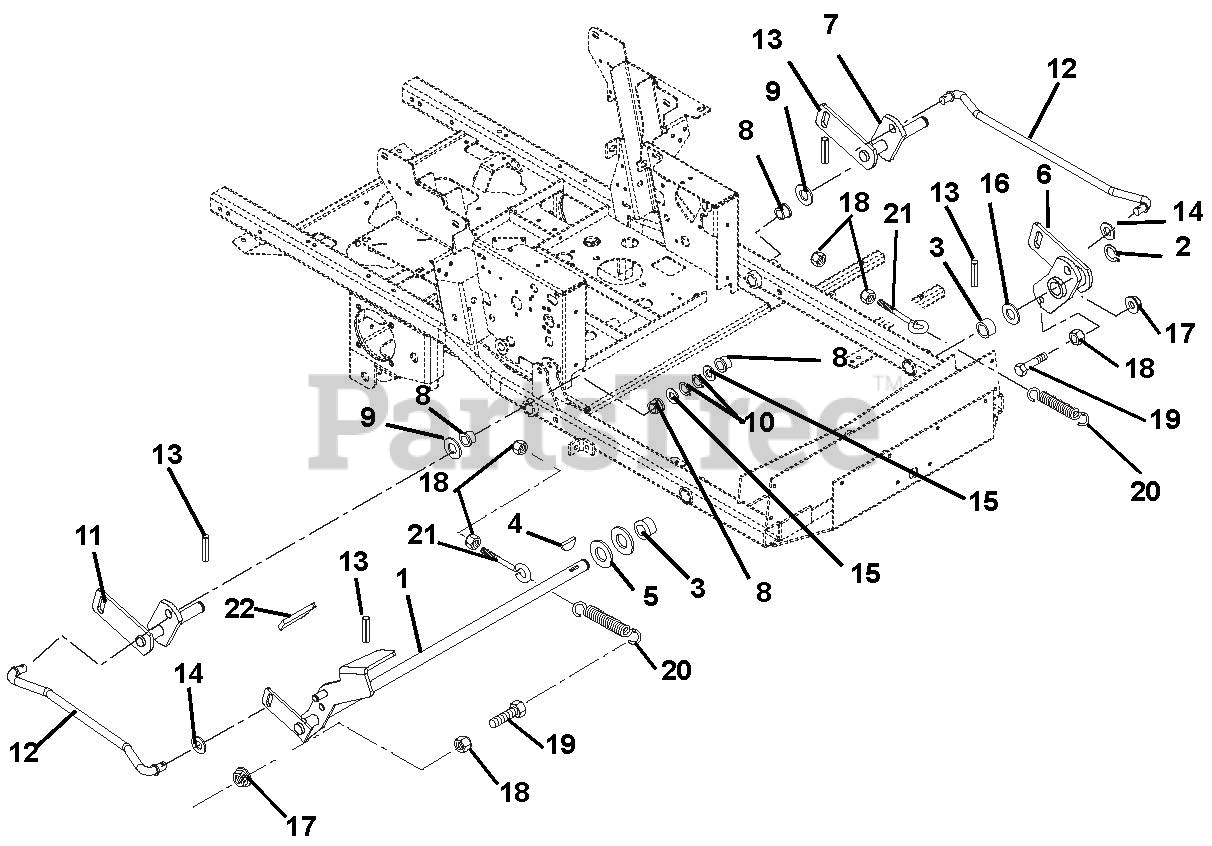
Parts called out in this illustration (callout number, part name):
1	Lift, Mechanical Mower
1	Lift, Hydraulic Mower
2	Ring, Retaining External 1.00 x .078
3	Bushing, 1.00 x 1.12 x .75 x 1.375
4	Key, Woodruff .25 x 1.00
5	Washer, Flat Steel 1.062 x 2.00 x .134
6	Weldment, Lift Arm Front
7	Weldment, Left Hand Rear Lift Arm
8	Bushing, Flange Nylon .762 x 1.00 x .58 x 1.48
9	Washer, Hardened Steel .758 x 1.23 x .031
10	Ring, Retaining External .689 x .077
11	Weldment, Right Hand Rear Lift Arm
12	Rod, Lift Assist
13	Pin, Roll .250 x 1.25 Stainless Steel
14	Washer, Flat-Steel .630 x 1.25 x .062
15	Washer, Flat Steel .755 x 1.25 x .125
16	Washer, Hardened Thrust 1.00 x 1.55 x .03
17	Nut, Locking Top Flange .38-16
18	Nut, Hex .38-16
19	Bolt, Hex .38-16 x 1.75 Grade 5
20	Spring, Tension .162 x 1.25 x 8.25
21	Bolt, Eye .375-16 x 2.50
22	Grip, Foot Pedal
